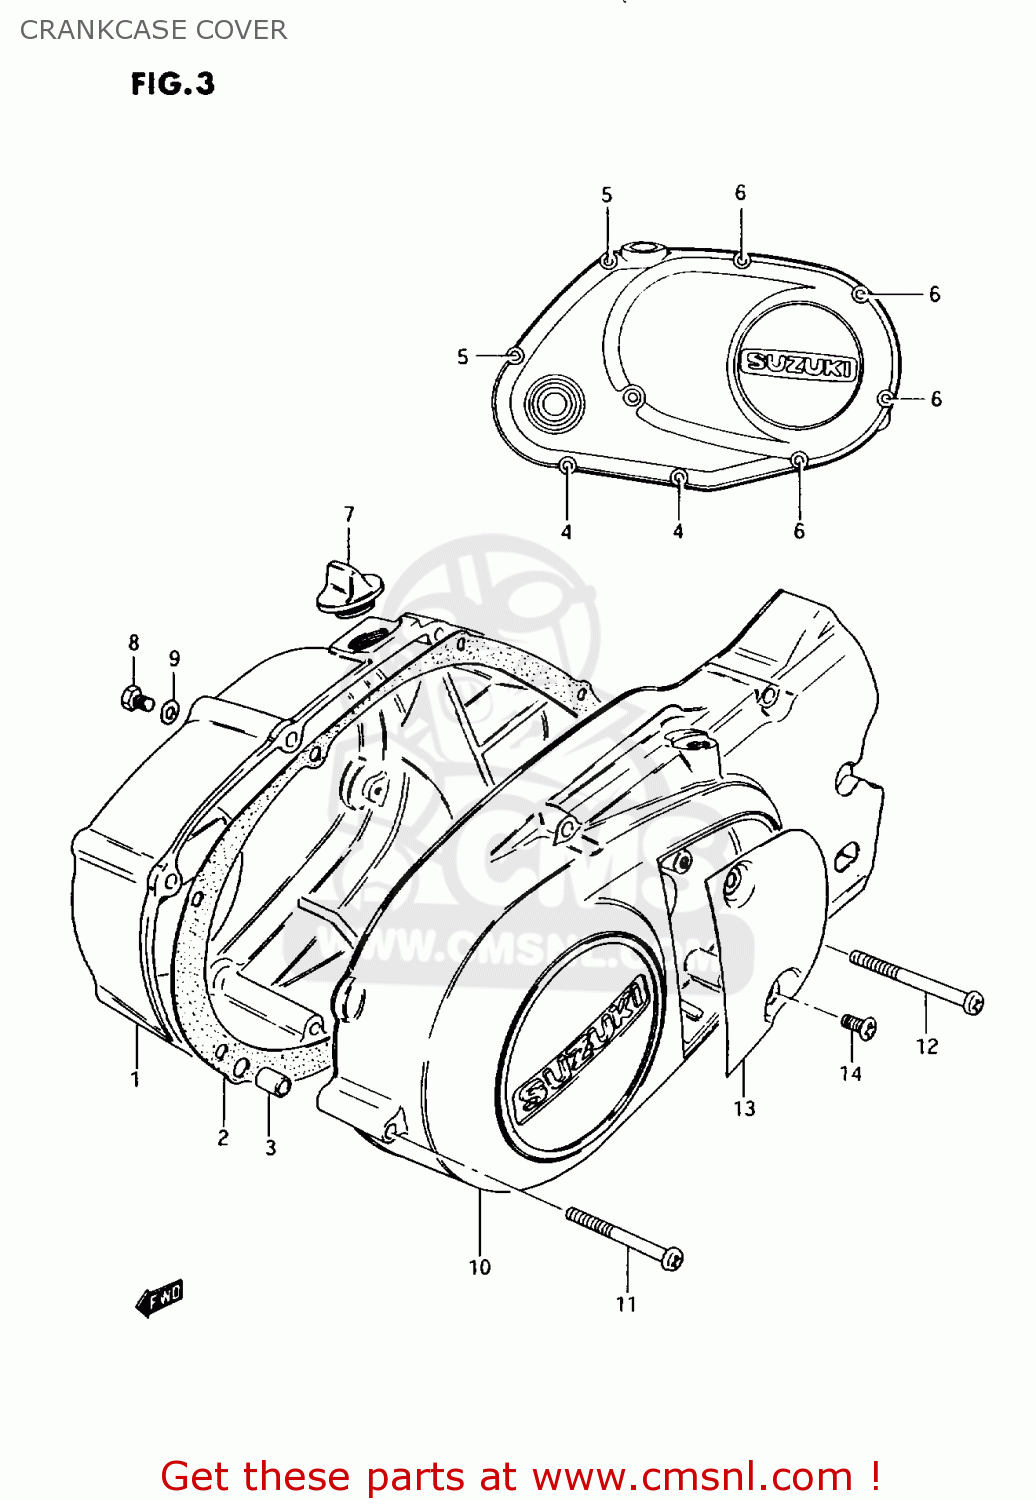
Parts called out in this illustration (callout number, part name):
1	COVER,CLUTCH
2	GASKET,CLUTCH COVER (NAS)
3	PIN
4	SCREW
5	SCREW
6	SCREW
7	PLUG SET
8	SCREW(6X10)
9	GASKET(6.2X11X1) (NAS)
10	COVER,MAGNETO
11	SCREW
12	SCREW
13	CAP,CLUTCH RELEASE ADJUST
14	SCREW
